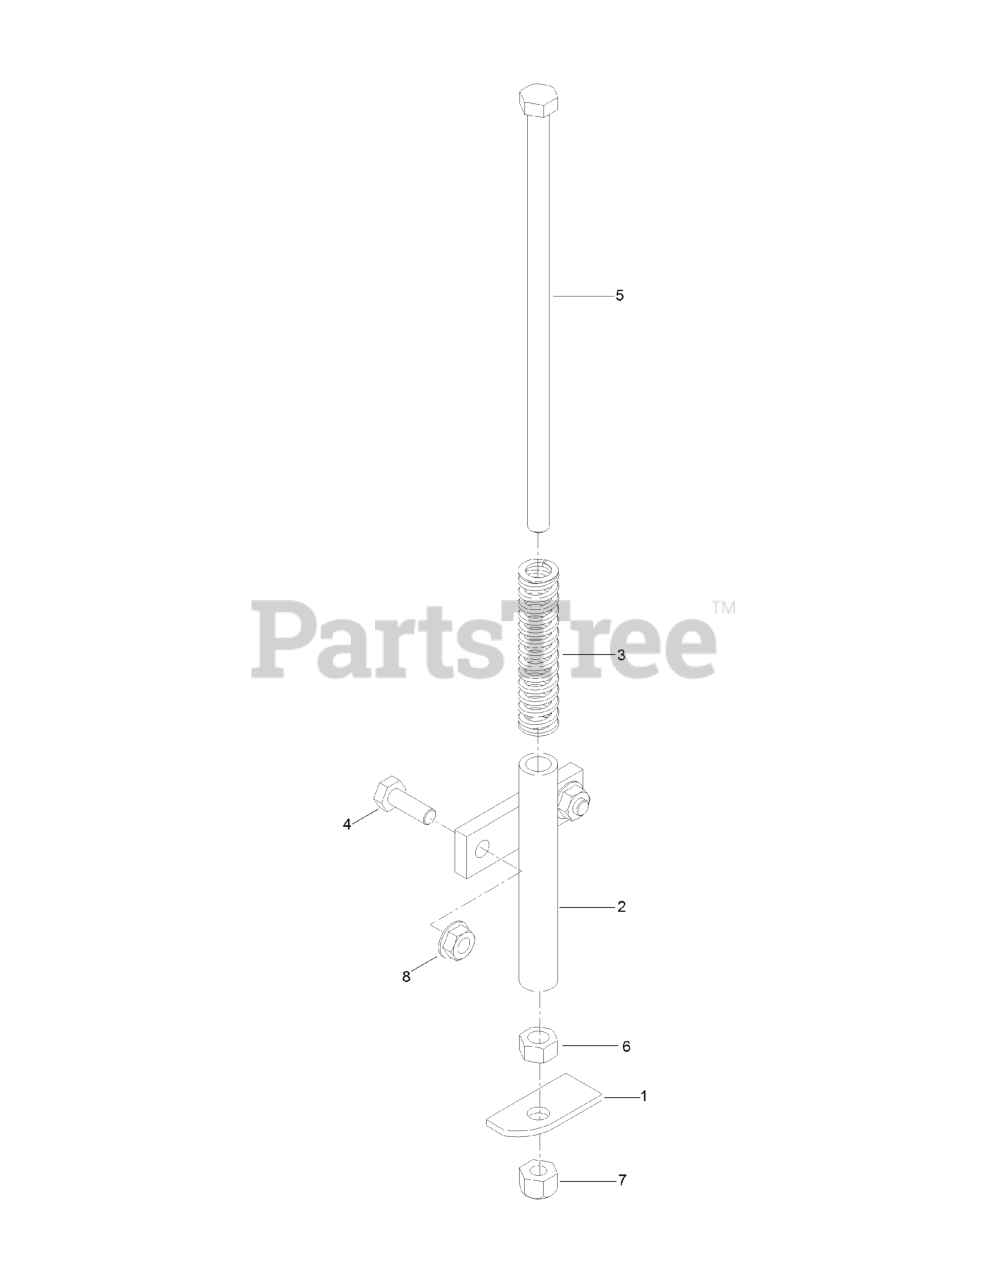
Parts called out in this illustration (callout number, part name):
1	Plate-Switch
2	MOUNT-SPRING, SEAT
3	SPRING-SWITCH, SEAT
4	SCREW-HH
5	SCREW-HH
6	NUT-HEX
7	NUT-LOCK, NI
